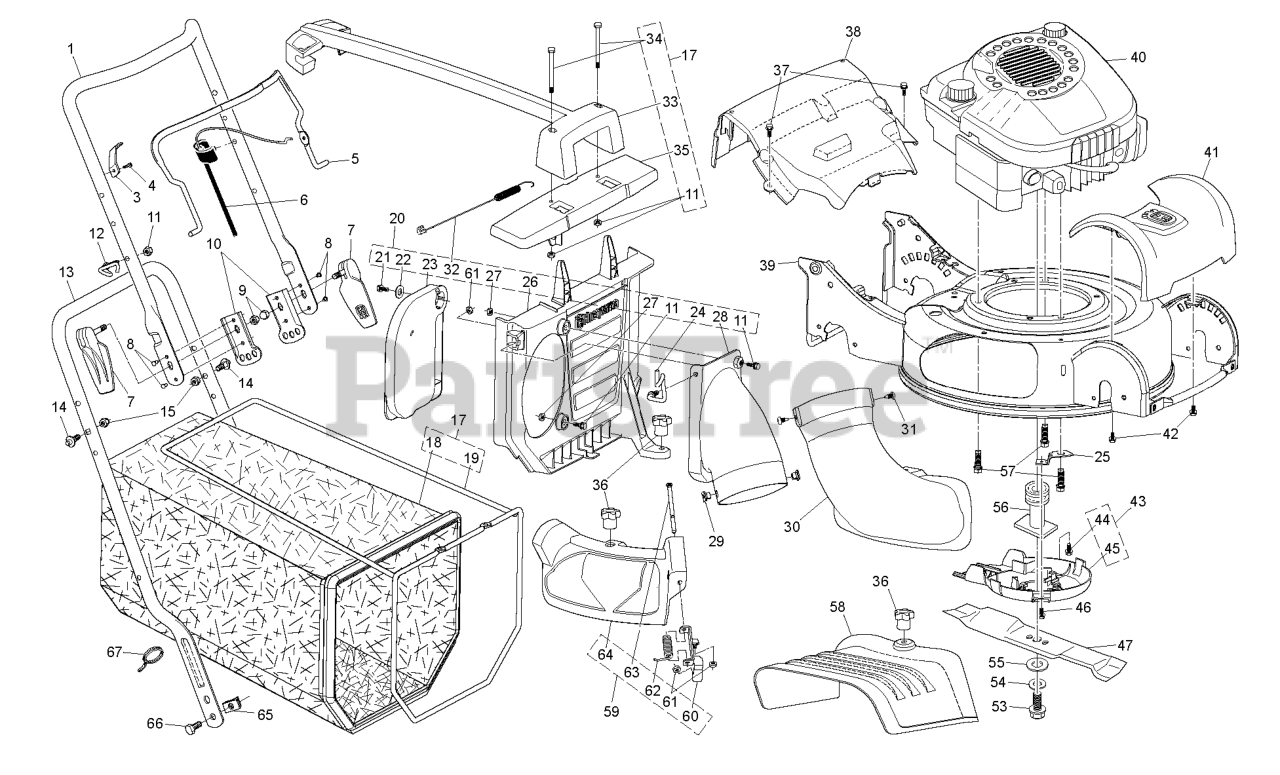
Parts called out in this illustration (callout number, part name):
1	HANDLE.ASM.UP.W/ADJ.BKT
3	BRACKET
5	BAIL CONTROL
6	CABLE.MZR.47.75.SNAP-IN.PU.L
7	ASM.QUICK.RELEASE
9	Locknut, Hex 1/4-20
10	BRACKET.ADJ.3POS.GREY
11	BOLT SHOULDER
12	RB GUIDE.ROPE.STD.BLK.ZIN WSL
14	STUD.QUICK.ADJUST
15	NUT.LOCK.5/16-18
22	WASHER
25	BRACKET
27	NUT
31	SCREW T-30 1/4-20 X
36	KNOB.MULCH.DOOR
37	SCREW, HEX WASHER HEAD
42	SCREW.HWH.13-16-5.8.BZP
44	HINGE SCREW
46	SCREW.HEX.WSH
47	BLADE.SWEPT.WING.45CM.H.TREAT
53	BOLT.HD.HEAD.3/8-24X2.50 (2 2)
54	LOCKWASHER
55	WASHER,HARDEN
56	ADAPTER.BLADE
57	BOLT 3/8-16X1-1/8
61	NUT.HEX.FLANGE.1/4
62	SPRING.MULCH.DOOR
63	ROD.HINGE.1/4"3.82"
64	DOOR.MULCH.GREY
67	TIE GUIDE
